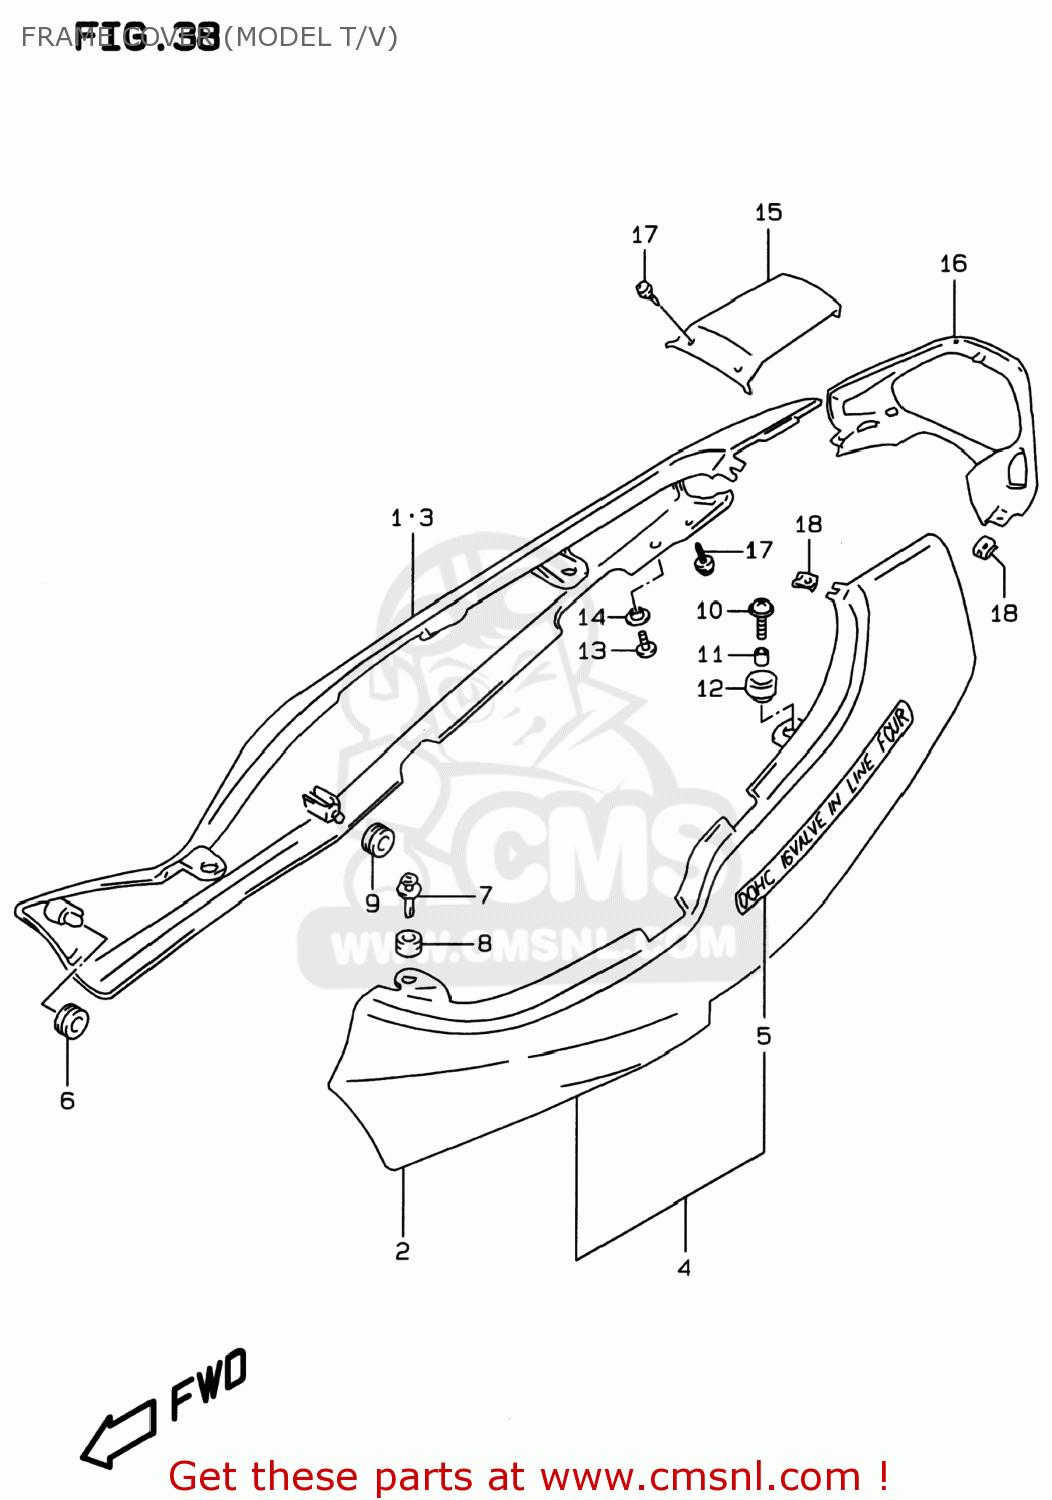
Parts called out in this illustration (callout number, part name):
1	COVER,FRAME,RIGHT
2	COVER,FRAME,LEFT
3	COVER COMP,FRAME,RIGHT
4	COVER,FRAME,L(RED)
5	EMBLEM,FRAME COVER
6	CUSHION,FRAME COVER FR
7	CLIP
8	CUSHION
9	CUSHION
10	SCREW(6X20)
11	SPACER(6.5X10X9.4)
12	CUSHION
13	SCREW
14	WASHER(6.3X16X1.5)
15	COVER,FRAME CTR
16	COVER,FRAME RR
17	SCREW
18	NUT
